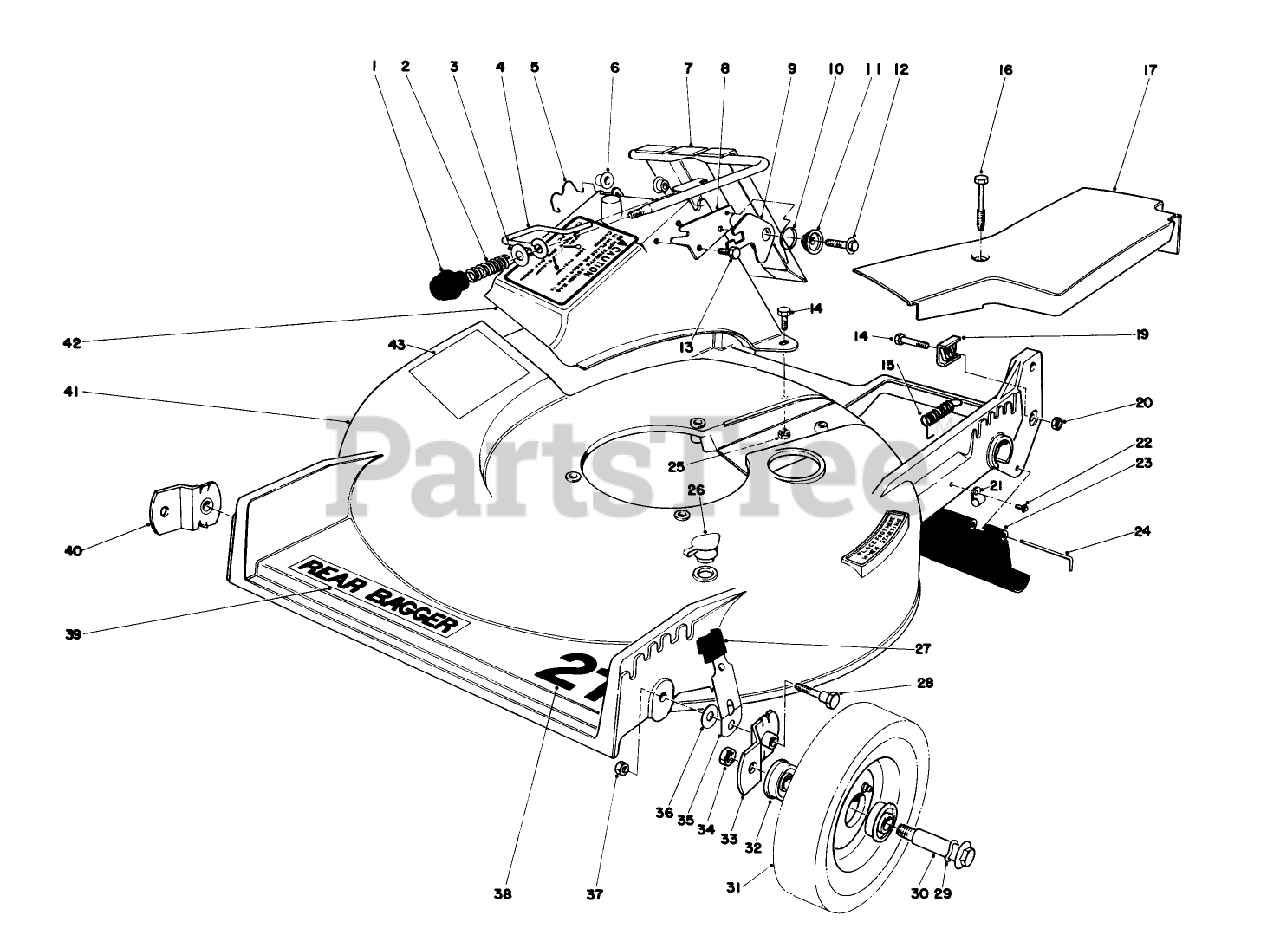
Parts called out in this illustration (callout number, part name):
2	COMPRESSION SPRING
3	WASHER
4	DOOR LATCH
5	DOOR RETAINER
6	BUSHING-NYLON
8	DOOR LATCH PLATE
10	TORSION SPRING
13	SCREW-HWH
14	SCREW-HH
15	IDLER SPRING
16	SCREW-HWH
19	CLAMP-CABLE
20	NUT-JAM
21	CLAMP-NYLON
22	SCREW-HWH
23	SHIELD - TRAILING
25	NUT-LOCK, NI
26	WASHOUT PLUG
27	KNOB-ARM
28	PIVOT SCREW
29	SPRING WASHER
32	BEARING-BALL
33	PIVOT ARM ASM A
36	WASHER-PIVOT
40	PIVOT ARM ASM
42	DISCHARGE CHUTE *B
